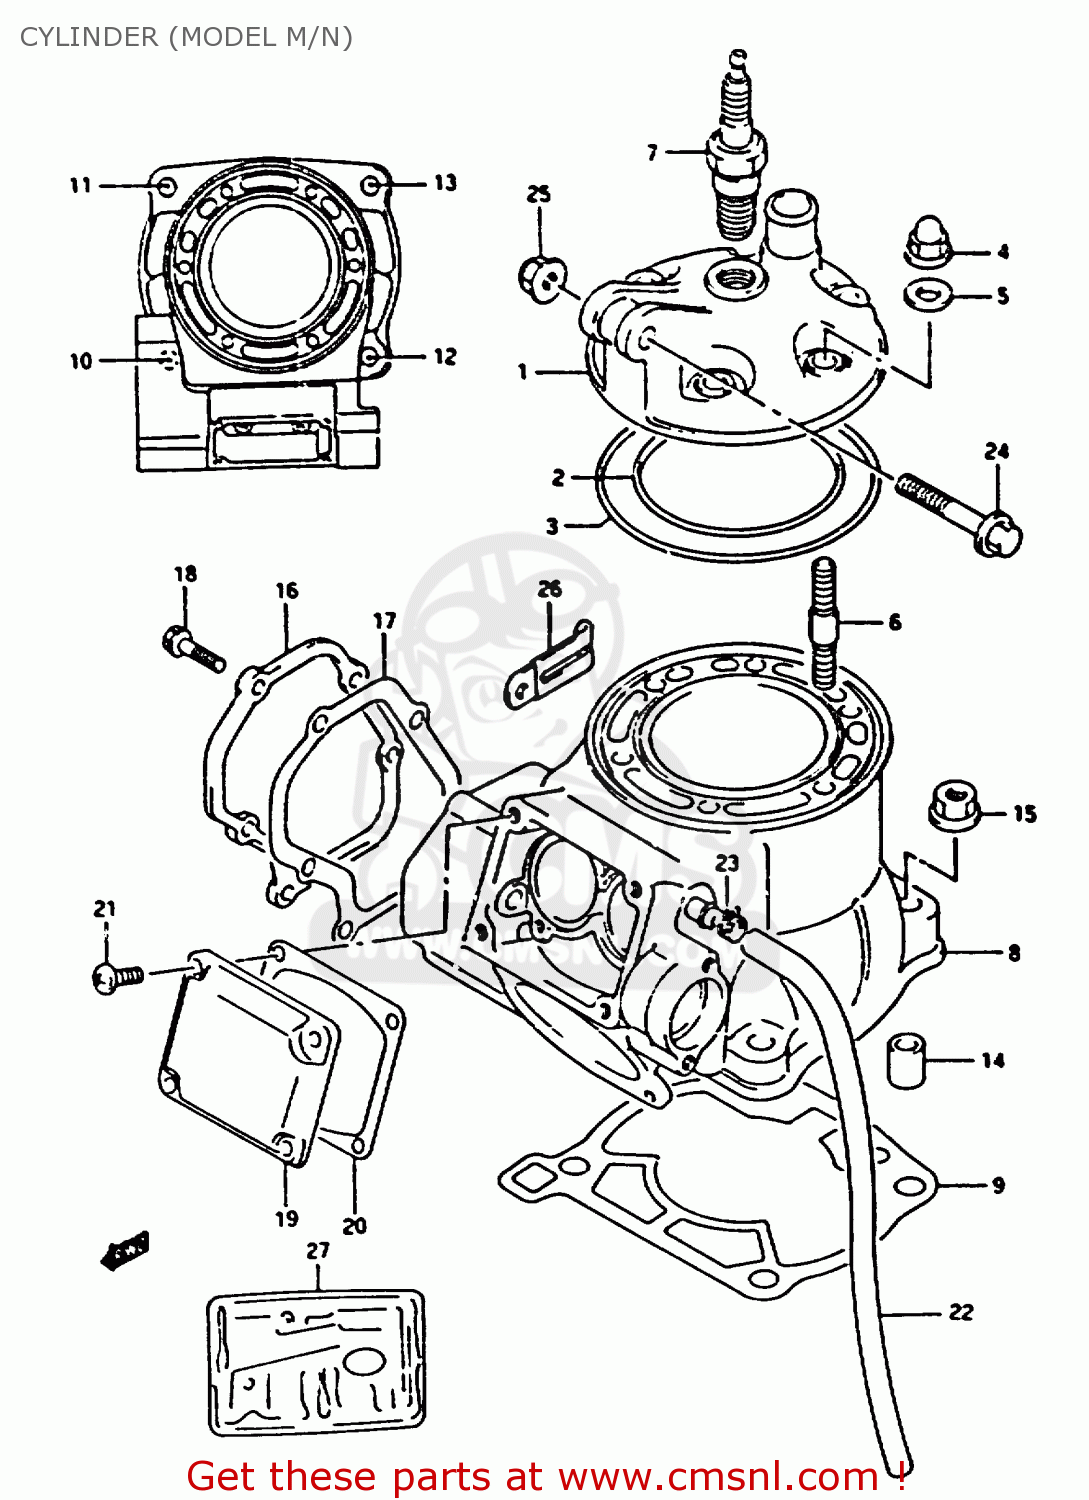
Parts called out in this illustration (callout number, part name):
1	HEAD,CYLINDER
2	O RING,CYLINDER HEAD NO.1
3	O RING,CYLINDER HEAD NO.2
4	NUT
5	GASKET(8.5X17X2.3) (NAS)
6	BOLT,STUD
7	PLUG,SPARK(R4118S-8)
8	CYLINDER
9	GASKET,CYLINDER (NAS)
10	STUD 10X30
11	STUD BOLT
12	STUD BOLT (L:40)
13	BOLT,STUD
14	PIN
15	NUT
16	COVER,CYLINDER NO.1
17	GASKET,CYLINDER COVER (NAS)
18	BOLT
19	COVER,CYLINDER NO.2
20	GASKET,CYLINDER COVER (NAS)
21	SCREW
22	HOSE
23	CLAMP
24	BOLT(8X45)
25	NUT
26	CLAMP L:35
27	GASKET SET
28	CLAMP
29	GASKET SET
